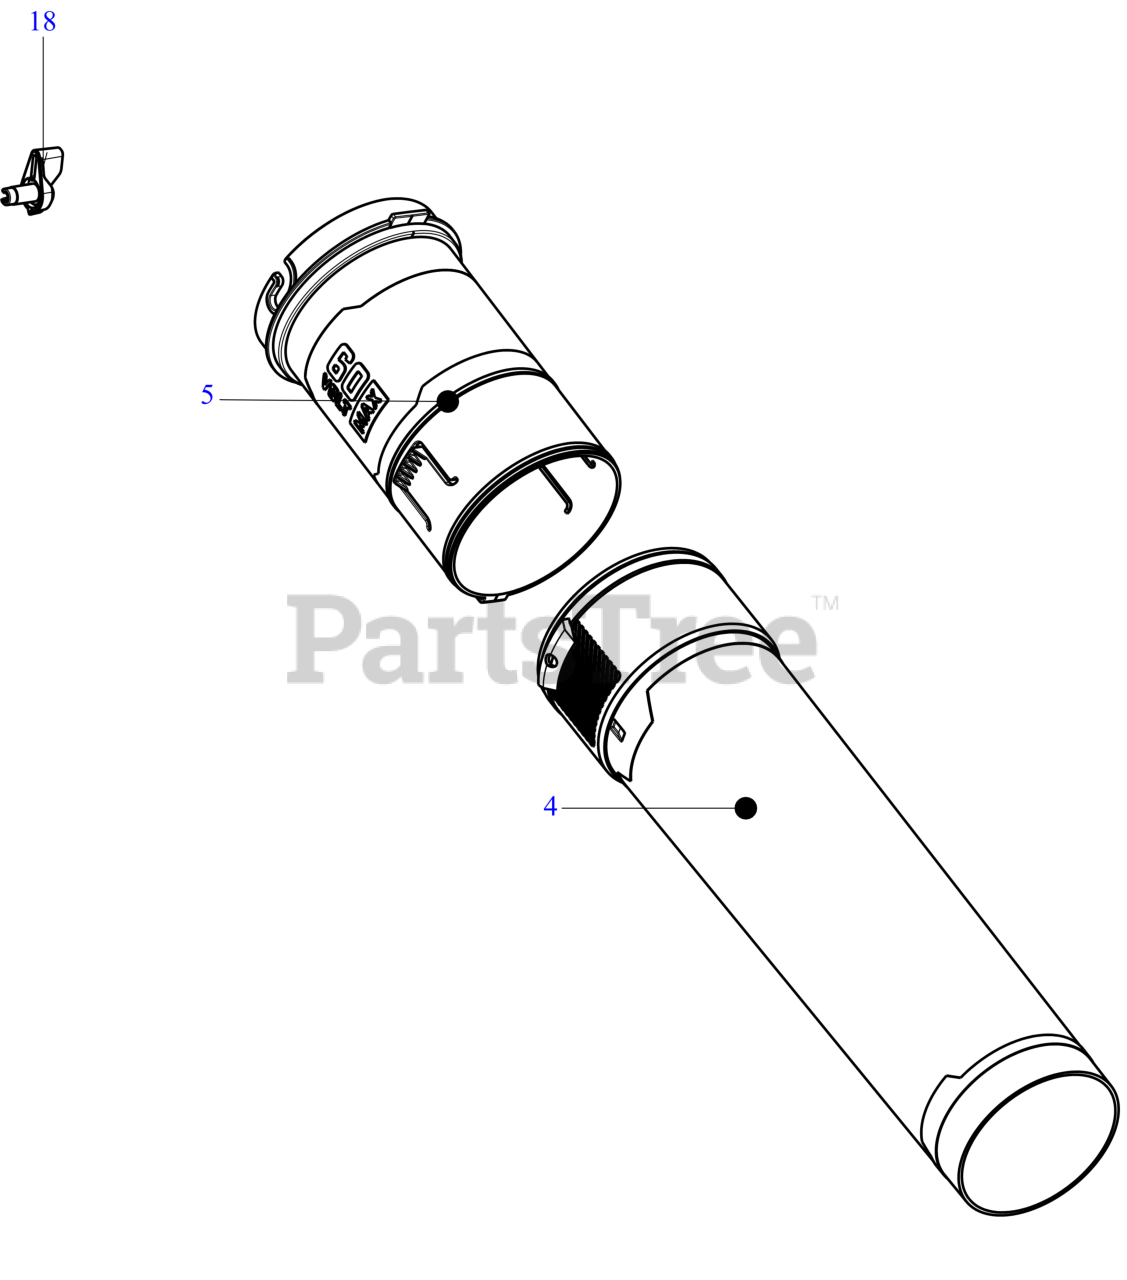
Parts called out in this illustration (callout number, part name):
4	BLOWER TUBE
5	CLEAR BLOWER TUBE
18	SPEED SELECT ACTUATOR
